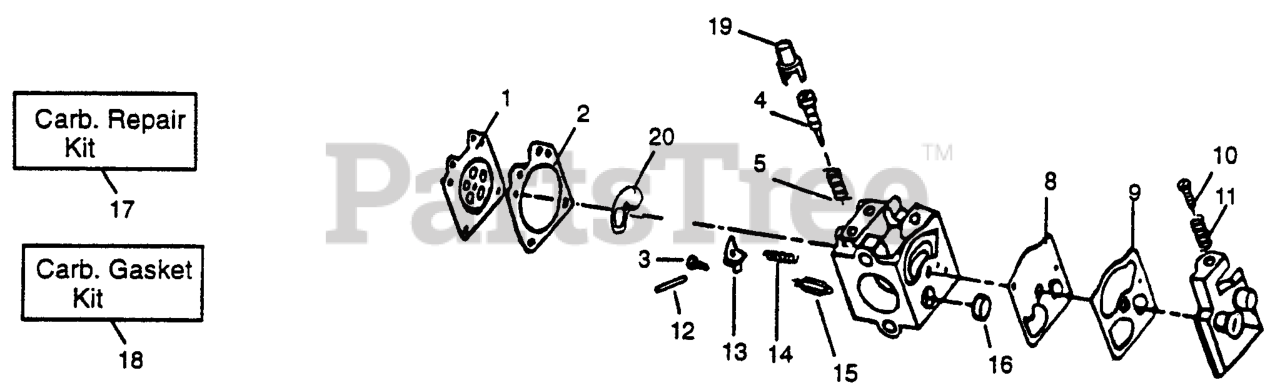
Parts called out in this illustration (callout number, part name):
1	DIAPHRAGM
2	GASKET-METER DIAP
4	Mixture Needle
5	Mixture Needle Spring
8	DIAP FUEL PUMP
9	GASKET-FUEL PUMP
10	SCREW-IDLE SPEED
11	IDLE SCREW SPRING
12	PIN
13	LEVER
14	Metering Lever Spring
15	INLET NEEDLEVALVE
16	SCREEN-DUTCH TWILL INLE
17	KIT-CARB. KWIK REPAIR
18	INQUGASKET DIAPHRAGM
19	LIMITER CAP
